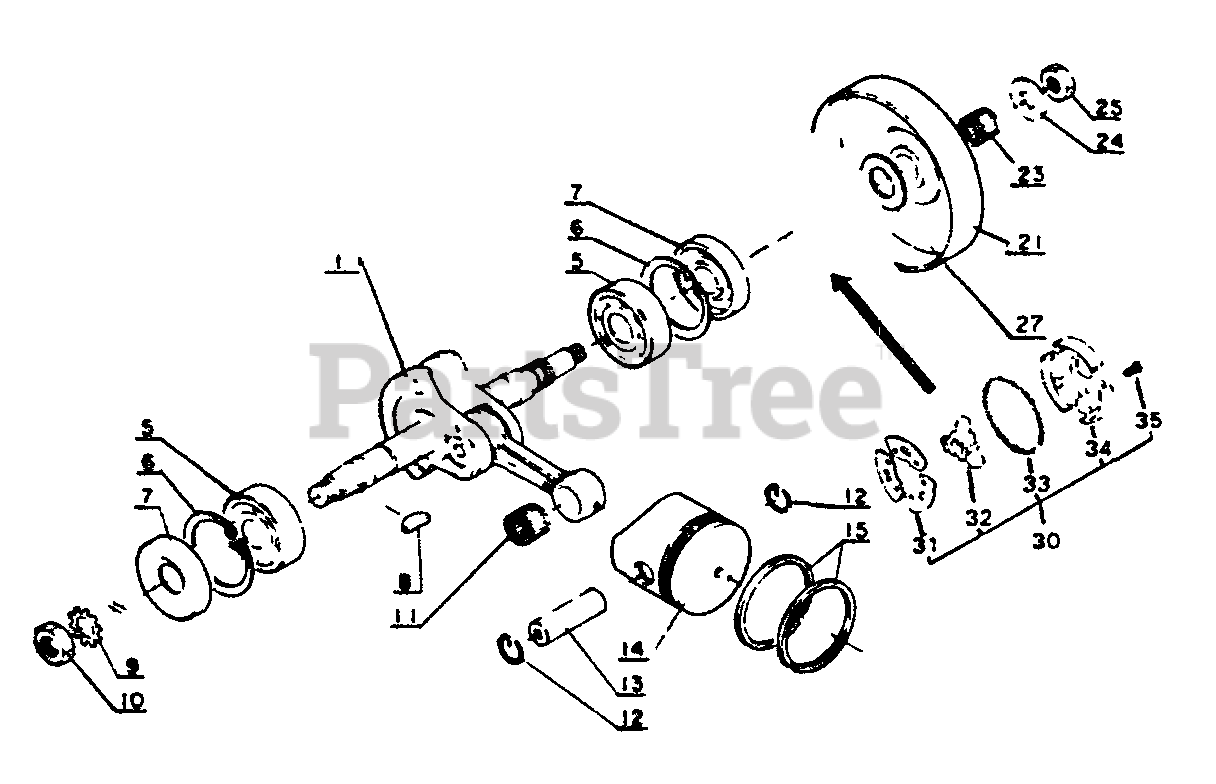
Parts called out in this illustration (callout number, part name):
1	CRANKSHAFT ASSY
5	BEARING, BALL - 6201
6	RING, RETAINING - 32
7	SEAL, OIL
9	LOCKWASHER - 8
11	BEARING, NEEDLE
12	RING, RETAINING
13	PIN, PISTON
15	RING, PISTON
21	CASE, CLUTCH
23	BEARING, NEEDLE
24	WASHER, CLUTCH
25	LOCKNUT - 6
27	WASHER, CLUTCH
30	CLUTCH ASSY
31	PLATE, CLUTCH
32	HUB, CLUTCH
33	SPRING, CLUTCH
34	CLUTCH SHOE SET
35	SCREW - 4X8
